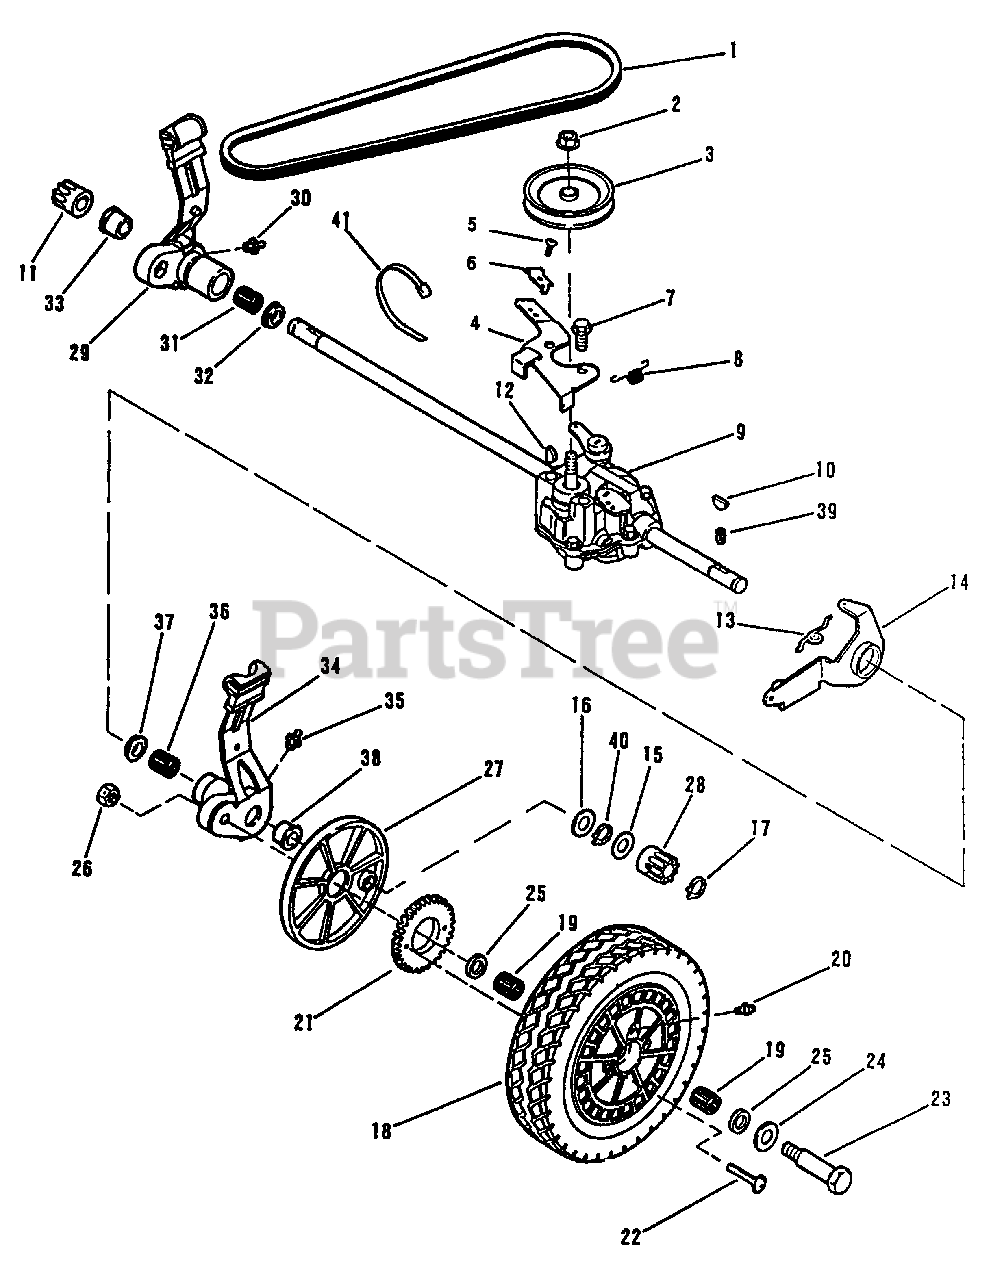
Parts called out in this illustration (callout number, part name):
1	V-Belt
2	Locknut
3	Transmission Pulley
4	Linkage Plate & Screw Kit
5	Screw-Clamp to Linkage Plate
6	Clamp
7	Screw-Plate to Transmission
8	Spring
9	Transmission
10	Key-Pinion to Shaft
11	Drive Pinion-R.H.
12	Key-Pulley to Transmission
13	Link
14	Actuator Arm and Bushing
15	Thrust Washer
16	Thurst Washer
17	Retaining Ring
18	Wheel-Tire and Bearing Assy
19	Needle Bearing
20	Grease Fitting
21	Gear
22	Screw-Gear to Wheel
23	Shoulder Bolt-Rear Wheel
24	Flat Washer
25	Felt Washer
26	Nut-Wheel to Height Adjust Arm
27	Wheel Cover
28	Drive Pinion-L.H.
29	Height Adjust Arm Assembly-R.H.
30	Grease Fitting
31	Needle Bearing
32	Seal
33	Flange Bearing
34	Height Adjust Arm Assembly-L.H.
35	Grease Fitting
36	Needle Bearing
37	Seal
38	Flange Bearing
39	Spring-Pinion Key
40	Retaining Ring
41	Tie Strap
